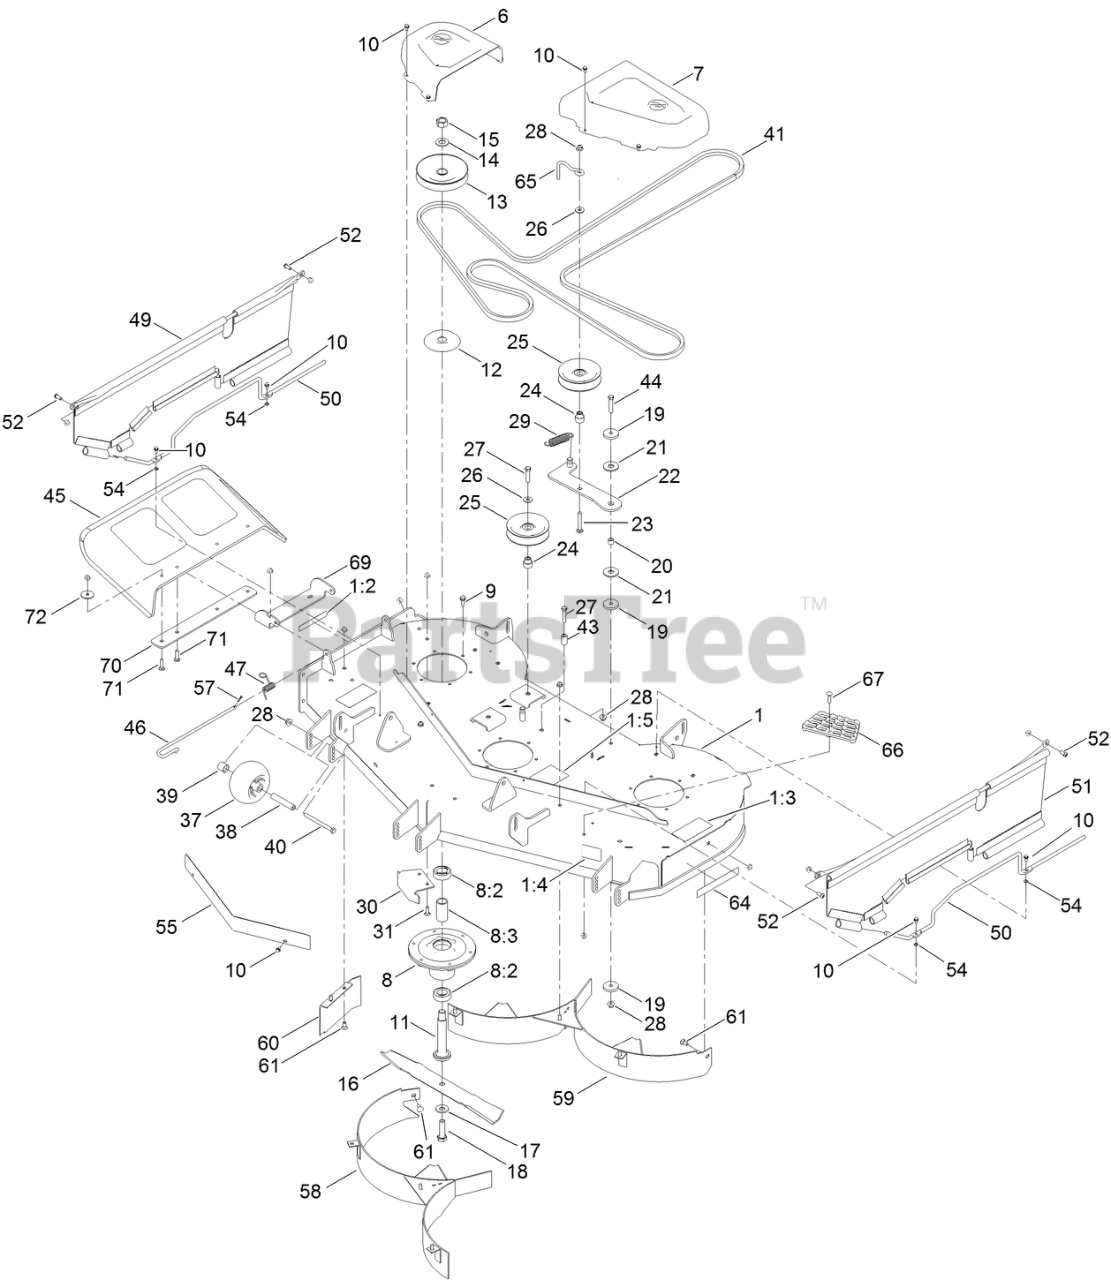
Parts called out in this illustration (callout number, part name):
1	54in DECK ASM
1:2	DECAL-DANGER
1:3	DECAL-DANGER, DECK
1:4	DECAL-SCALP, ANTI
1:5	DECAL-ROUTING, BELT
6	COVER-BELT, RH
7	COVER-BELT, LH
8	SPINDLE ASM
8:2	BEARING-BALL
8:3	SPACER-BEARING
9	SCREW-TAPTITE
10	SCREW-HWH
11	SHAFT-SPINDLE
12	SHIELD-BEARING
13	PULLEY
14	WASHER
15	NUT-HEX
16	BLADE-MULCH, 18.75 INCH
17	WASHER-BELLEVILLE
18	SCREW-BLADE
19	WASHER-PLAIN
20	SPACER
21	WASHER-FRICTION, COMPOSITE
22	IDLER ARM ASM
23	SCREW-CARR
24	BUSHING-IDLER
25	PULLEY-IDLER, FLAT
26	WASHER-HARDENED
27	SCREW-HH
28	NUT-HF, NI
29	SPRING-EXTENSION
30	BAFFLE-CUTOFF
31	SCREW-CARR
37	ROLLER-SCALP, ANTI
38	TUBE-SPANNER
39	SPACER-AXLE, REAR
40	SCREW-HH
41	V-BELT
43	SPACER-FENDER
44	HHCS 3/8-16 X 2, GR5, CZ
45	DEFLECTOR
46	PIN-CHUTE
47	SPRING-TORSION
49	ROD SUPPORT, UPPER
50	ROD SUPPORT, LOWER
51	SIDE GUARD ASM
52	SCREW-HSBH
54	NUT-RETAINING
55	SHIELD-FRONT
57	PIN-COTTER
58	BAFFLE-RECYCLER
59	BAFFLE-RECYCLER, LH
60	GUARD-BAFFLE
61	BOLT-CARR
64	DECAL-RECYCLER
65	GUIDE-BELT, IDLER
66	STEP-DECK
67	BOLT-CARRIAGE
69	BRACKET-DEFLECTOR, UPPER
70	PLATE-DEFLECTOR
71	BOLT-CARRIAGE
72	WASHER-FLAT
